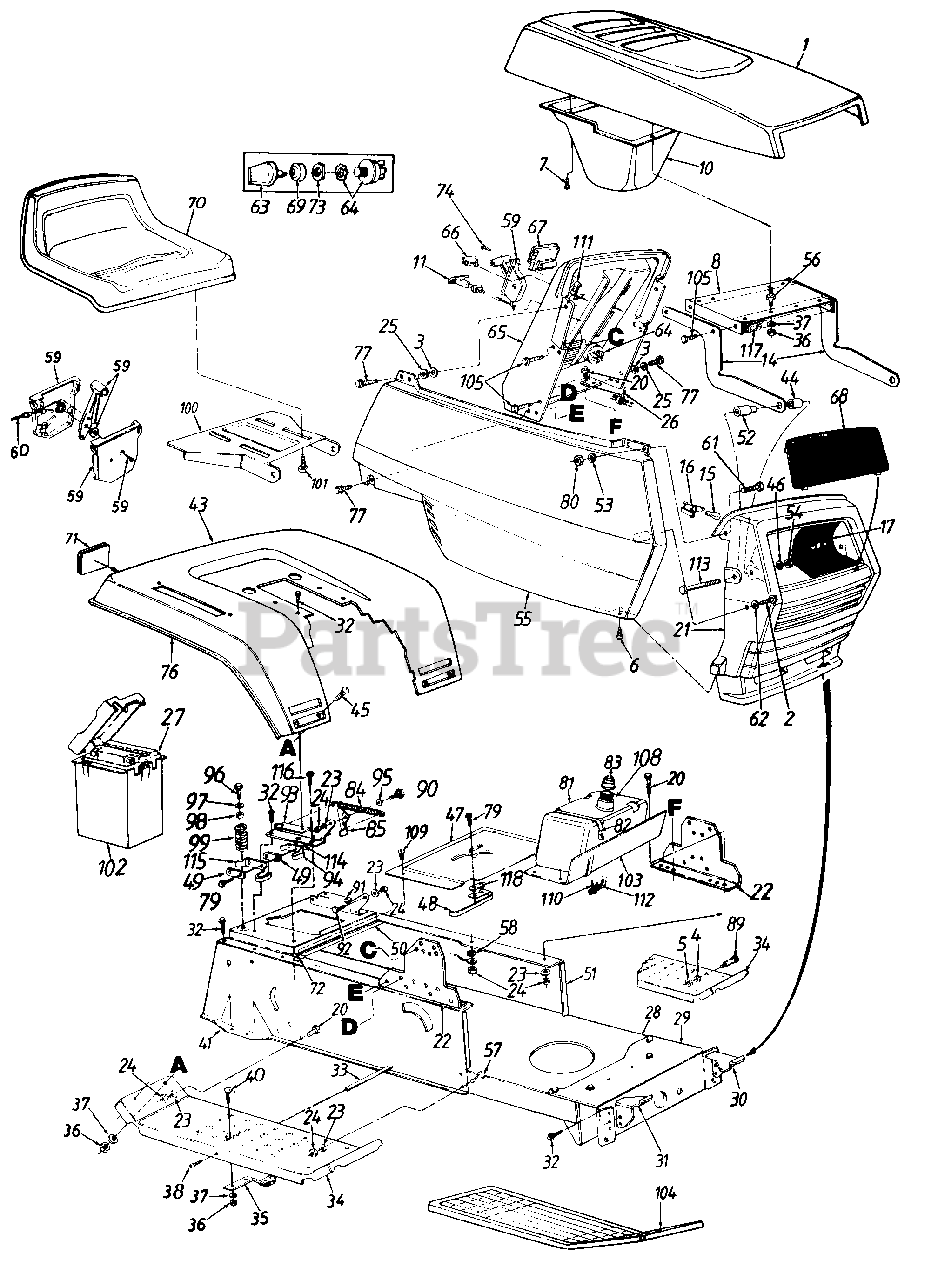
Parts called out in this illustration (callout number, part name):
3	Bolt Retainer 1/4" I.D.
4	L-Wash. 3/8" I.D.
5	Hex Nut 3/8-16 Thd.
6	Truss Mach. AB-Tap Scr. #10 x .5" Lg.
7	Hex Wash Hd. AB-Tap Scr. #8 x .5" Lg.
8	Hood Plate
11	Choke Control 29" Lg.
14	Hood Hinge
15	Lamp
16	Twist Lock-Lamp Socket
17	Reflector-Headlight
20	Hex Bolt 5/16-18 x .75" Lg.
21	Grille
22	Dash Support Bracket
23	L-Wash. 5/16" I.D.
24	Hex Nut 5/16-18 Thd.
25	Fl-Wash. 1/4" I.D. x .93" O.D.
26	Cable Tie
27	12 Volt Battery
28	Lower Frame
29	Front Pivot Brk't.
30	Grille Mount Brk't.-L.H.
31	Grille Mount Brk't.-R.H.
32	Hex Wash. Hd. AB-Tap Scr. 5/16 x .75" Lg.
33	Running Board Rod
34	Running Board
35	Blade Brake Ass'y.
36	Hex Nut 1/4-20 Thd.
37	L-Wash. 1/4" I.D.
38	Truss Mach. Scr. 5/16-18 x .75" Lg.
40	Carr. Bolt 1/4-20 x .62"
41	R.H. Side Frame
45	Carriage Bolt 1/4-20 x .50" Lg.
46	Fl-Wash. .328" I.D. x .68" O.D.
47	Transmission Panel
48	Reverse Safety Switch
49	Insulator Plate
50	Hitch Plate
51	L.H. Side Frame
52	Shld. Spacer .33" I.D.
53	Fl-Wash. .281" I.D. x .5" O.D.
54	Hex Cent. L-Nut 5/16-18 Thd.
55	Side Cover-R.H.
56	Double Ended Stud 1/4-20 Thd.
57	Truss Hd. Scr. 5/16-18 x 1.0" Lg.
58	Ext. L-Wash. 5/16" I.D.
59	Throttle Control Box Ass'y.
60	Throttle Control Wire 18.5" Lg.
61	Hex Bolt 1/4-20 x .62" Lg.
62	Fl-Wash. .281" l.D. x .73" O.D.
64	Ignition Switch
66	Light Switch
67	Ammeter
68	Lens
69	Ignition Switch Cap
70	Seat Ass'y.
71	Reflector
72	Speed Nut #10Z
73	Ignition Switch Nut
74	Truss Mach. AB-Tap Scr. #10 x .5" Lg.
76	Trim Strip-81"
77	Hex Wash. Hd. Tap Scr. 1/4 x.75" Lg.
79	Hex Wash. Hd. AB-Tap Scr. #8 x .50" Lg.
80	Hex L-Nut 1/4-20 Thd.
81	Fuel Tank
82	Cable Tie
83	Fuel Cap w/o Gasket
84	Ext. Spring 5.31" Lg.
85	Seat Lift Brkt.
89	Shoulder Bolt
90	Shld. Bolt .437" Dia. x .268"
95	Spr.-Wash..445" I.D.
96	Hex Wash. Hd. Tap Scr. 5/16-18 x 1" Lg.
97	Fl-Wash..344" I.D.
99	Compression Spring
100	Seat Pivot Bracket
101	Hex Tap Scr. 3/8-16 x .75"
102	Battery Box
103	Gasoline Tank Support
104	Foot Pad-L.H.
105	Hex Tap Scr. 1/4-20 x .5" Lg.
108	Fuel Cap Gasket
109	Truss Mach. Tap Scr. #10 x .5" Lg.
111	Speed Nut 1/4-20 Thd.
112	Fuel Line
113	Hex Bolt 5/16-18 x 2.75"
114	Insulator Boss Plate
115	Spring Switch
116	Truss Mach. Scr. 5/16-18 x . Lg.
118	Insulator Nut Plate
